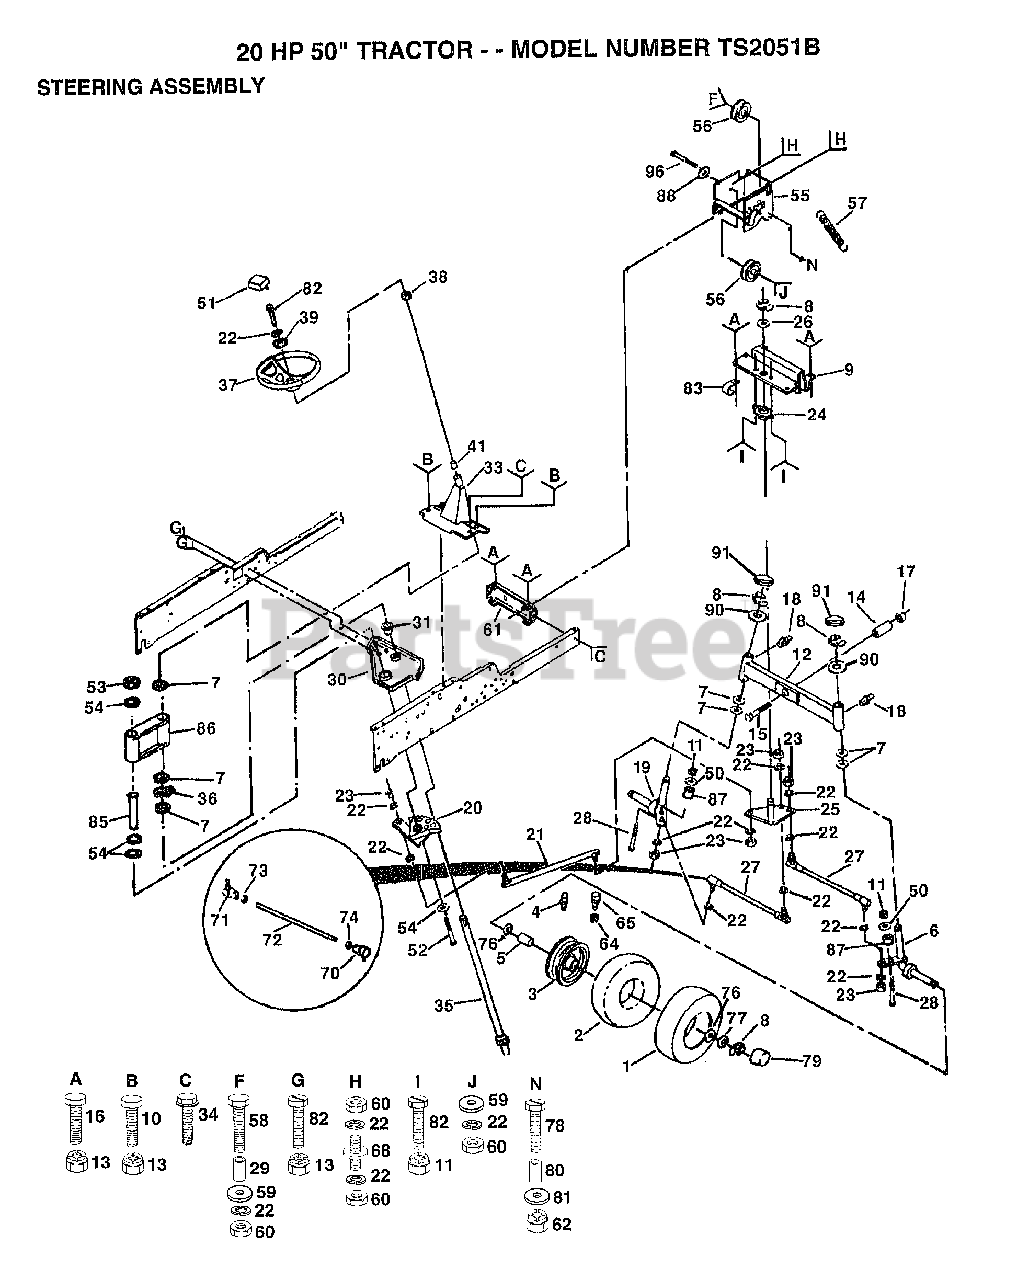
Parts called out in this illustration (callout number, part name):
2	TUBE.16X6.5/7.5-8
4	FITTING LT
5	"FLANGE, BEARING"
6	SPINDLE.ASM.RH
7	WASHER .T
8	RING
9	AXLE BRACKET T
13	NUT
14	SPACER BEARING
15	BOLT
16	BOLT
17	LOCKNUT M
18	ZERK M
19	SPINDLE.ASM.LH
20	SECTOR T
21	LINK.DRAG.T
22	LOCKWASHER
24	BUSHING BELLCRANK
25	"T, BELLCRANK"
26	WASHER
27	TIE ROD T
28	BOLT
29	BUSHING LT
31	"FLANGE GT, BEAR."
33	SUPPORT ASSY T
34	SCREW
35	SHAFT STEERING GT
36	KLIP RING
38	ADAPTER LT
39	WASHER T
40	SLEEV-STEERIN T
41	"T, BEARING"
50	WASHER T
51	ST WHL INSERT CAP
52	BOLT T
53	NUT LTV
54	WASHER GT
55	IDLER BRKT T
56	IDLER-INSIDE T
57	SPRING
58	BOLT
59	WASHER
60	NUT.HEX.3/8-16UNC
61	FRAME BRACKET GT
64	VALVE STEM LT
65	VALVE CAP
70	JOINT.RH
71	JOINT.LH
73	NUT
74	NUT
76	WASHER
77	WASHER
79	HUB CAP
80	SPLIT SPACER YTV
81	WASHER
82	BOLT
83	CLIP GTV
85	TUBE T
86	COLLAR
87	SPACER LT
88	WASHER T
90	WASHER
91	CAP
